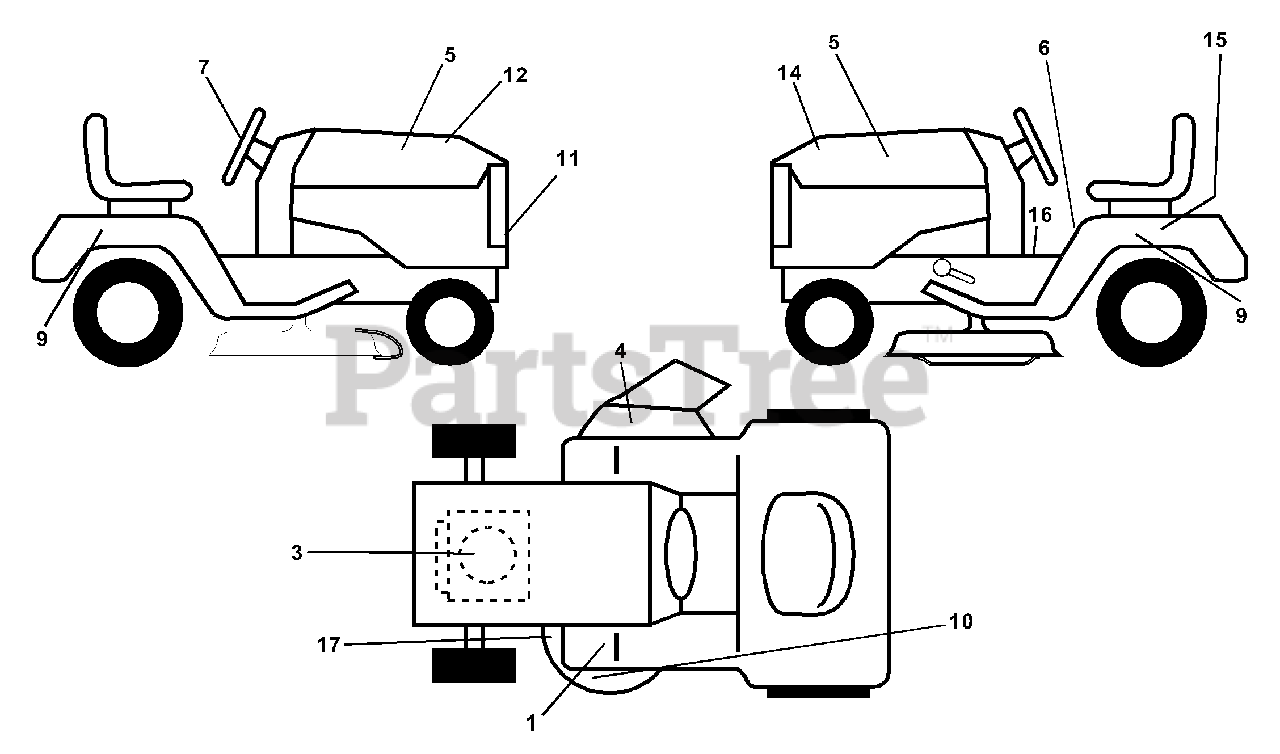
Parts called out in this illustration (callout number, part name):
1	Decal, Clutch/Brake Eng/Fr
3	Decal, Engine HP
4	Decal Warning
5	Decal, Pnl Sd
6	Decal, Fender Danger English
7	Decal Ins Str Wh
9	Decal Fender
10	Decal, Deck Grasseater
11	Decal, Grille Weedeater
12	Decal, Hood RH
14	Decal, Hood LH
15	Decal, Caution, Battery
16	Decal, Oper Sdl P/L Gear Dr Eng
17	Decal, V-Belt Sch.
